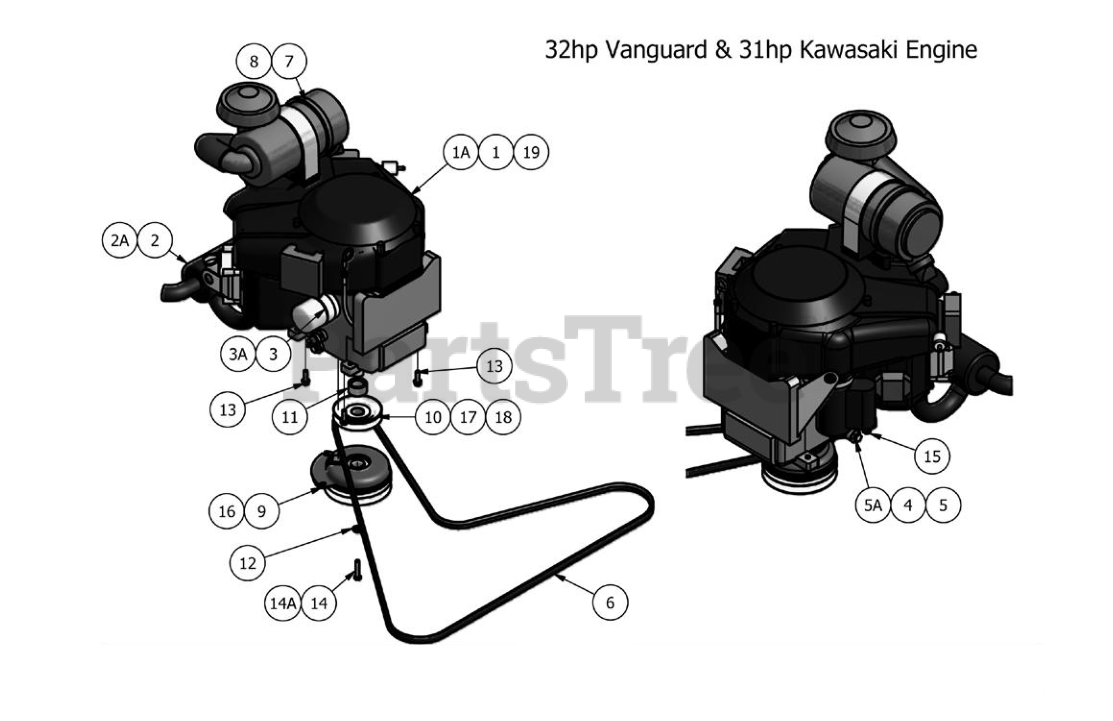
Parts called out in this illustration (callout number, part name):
1	32hp Vanguard Engine
1A	31hp Kawasaki Engine FX-850V-AS09R
2	32 HP Vanguard Exhaust
2A	Exhaust for 31hp Kawasaki
3	Oil Filter for Briggs 31HP and 35HP Vanguard
3A	Oil Filter -26hp & 19hp Kawasaki
4	Oil Drain Hose for 35/31hp Briggs
5	Adaptor for 35/31hp Briggs Oil Drain
5A	Oil Drain Valve - 26hp Kawasaki
6	Pump Belt for Pup, Lightning, AOS
7	Cannister Air Filter (Inner)
8	Cannister Air Filter (Outer)
9	Clutch Assembly
10	4 3/4" Motor Pulley
11	1 1/8 collar spacer
12	7/16" Lock Washer
13	3/8 x 1-1/8 Hex Washer Head Engine Bolt
14	7/16-20 x 2-1/2 GR 5 Hex Bolts Zinc (Vanguard Engine Only)
14A	M10 X 1.5 X 60MM (Kawasaki Engine Only)
15	M8- 1.25 Nut (Kawasaki Engine Only)
16	Clutch Pigtail
17	3/8" Set Screw
18	1/4" x 1 Square Key
19	AOS Fuel Line Assembly, 35 Vanguard - Complete
